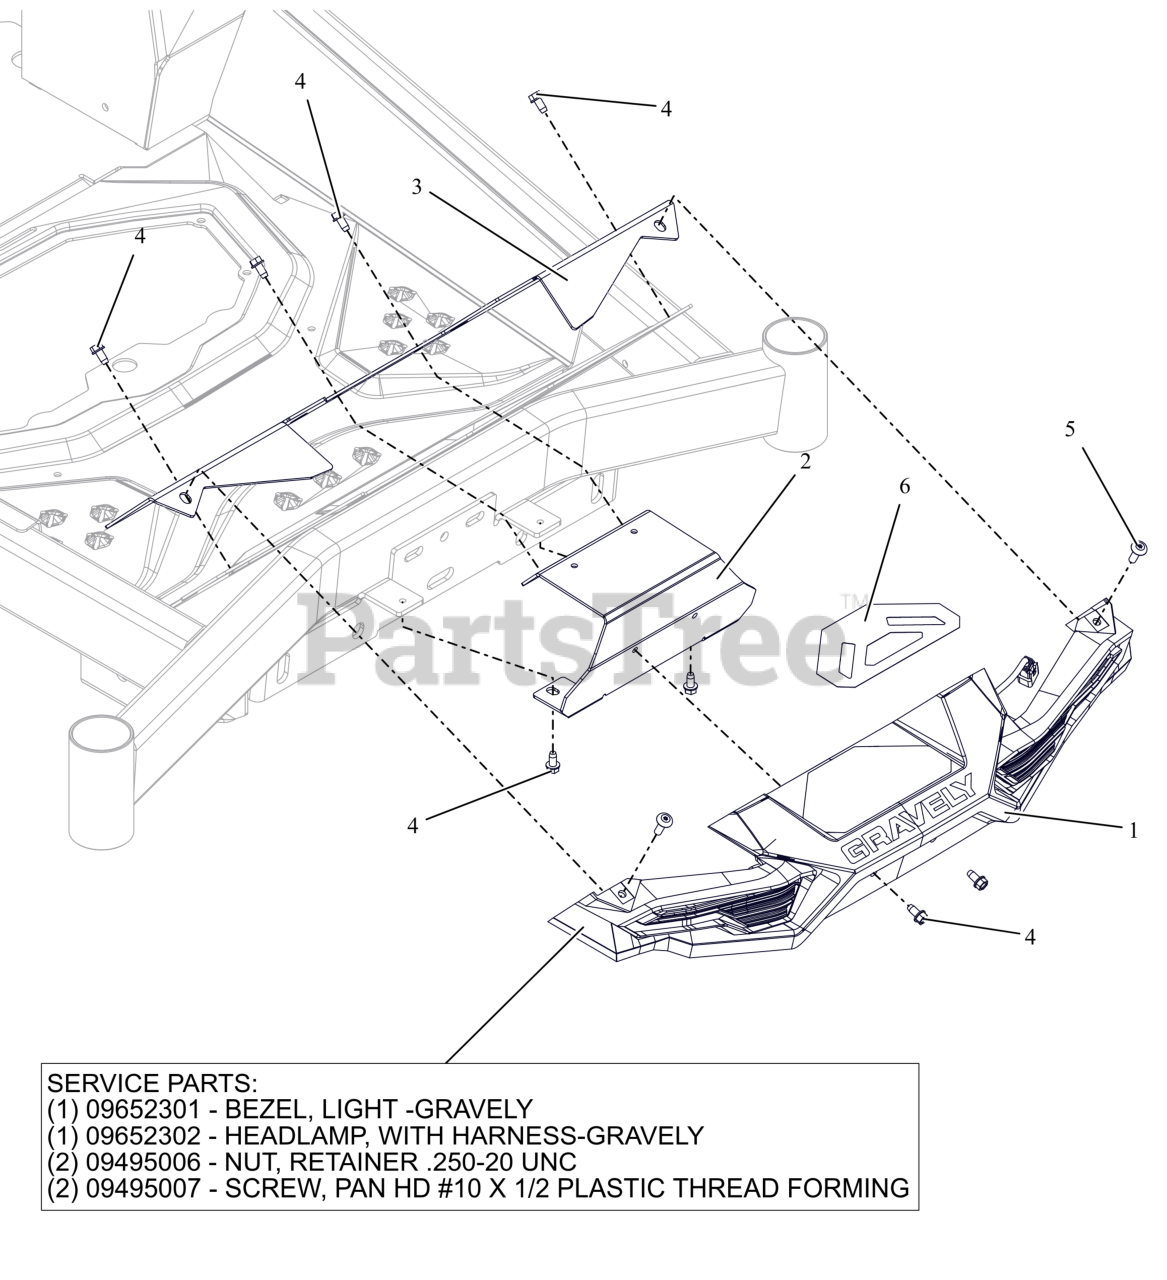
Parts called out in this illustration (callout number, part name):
1	LIGHT ASSY- HEADLIGHT GRAVELY
2	BRKT-FRT FACIA-LOWER-GRAVELY
3	BRKT- FRT FACIA UPPER-GRAVELY
4	SCR-TAP .25X.50 HWH ZB500
5	SCR-MCH .25-20X.75 TXTR ZB500
6	GRIP- TAPE-FRONT STEP-GRAVELY
